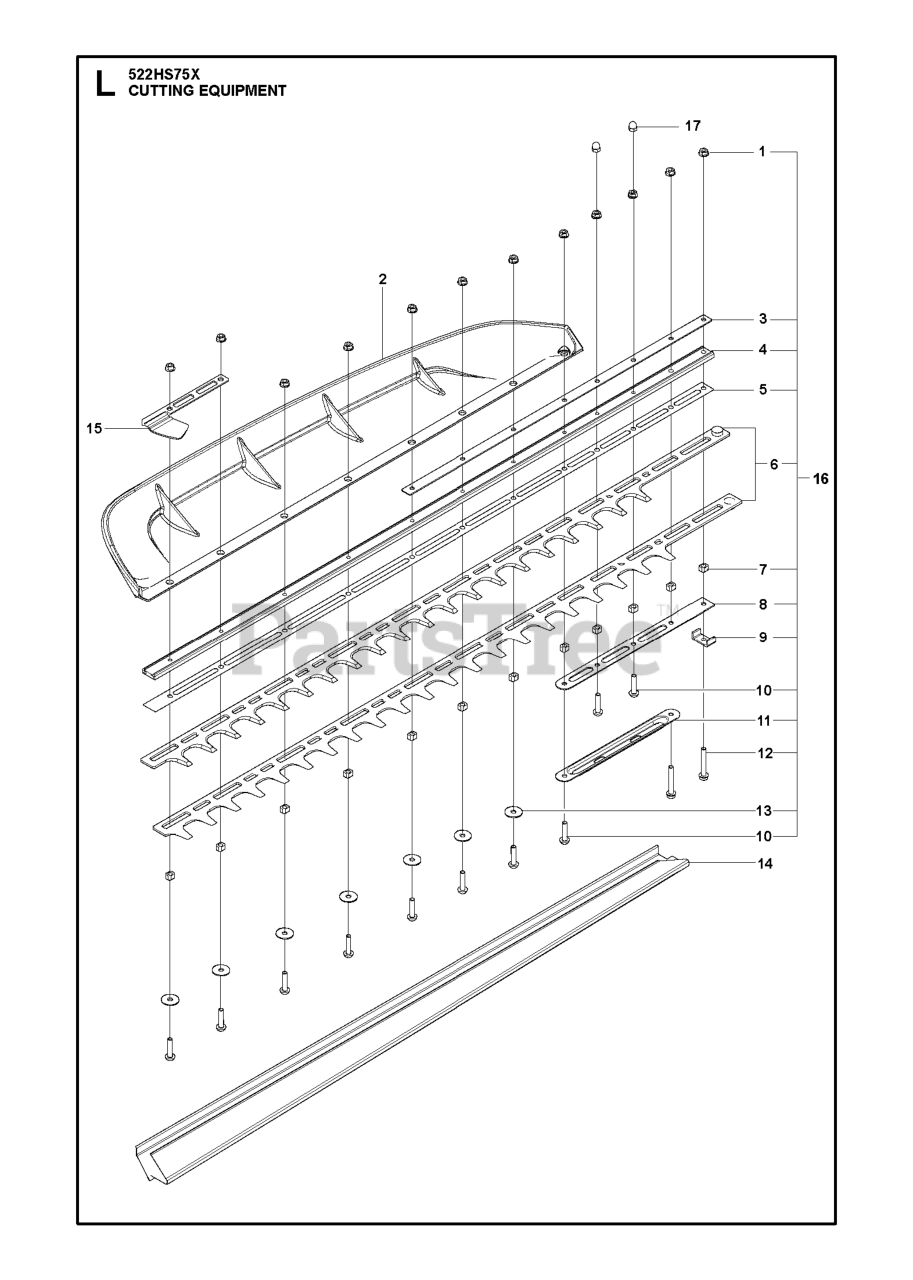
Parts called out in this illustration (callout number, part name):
1	NUT HEXAGON LOCK WITH FLANGE M
2	PLATE LEAF CATCHER ASSY HUSQVA
3	BAR PLATE UPPER
5	WEAR PLATE
7	SPACER CUTTING DECK
8	BAR PLATE LOWER
10	SCREW HEXALOBULAR SOCKET BUTTO
11	BAR PLATE LOWER
13	WASHER PLAIN 5.5X19X1.2 ST TBO
14	TRANSPORT GUARD
15	PROTECTION BLADE TIP
